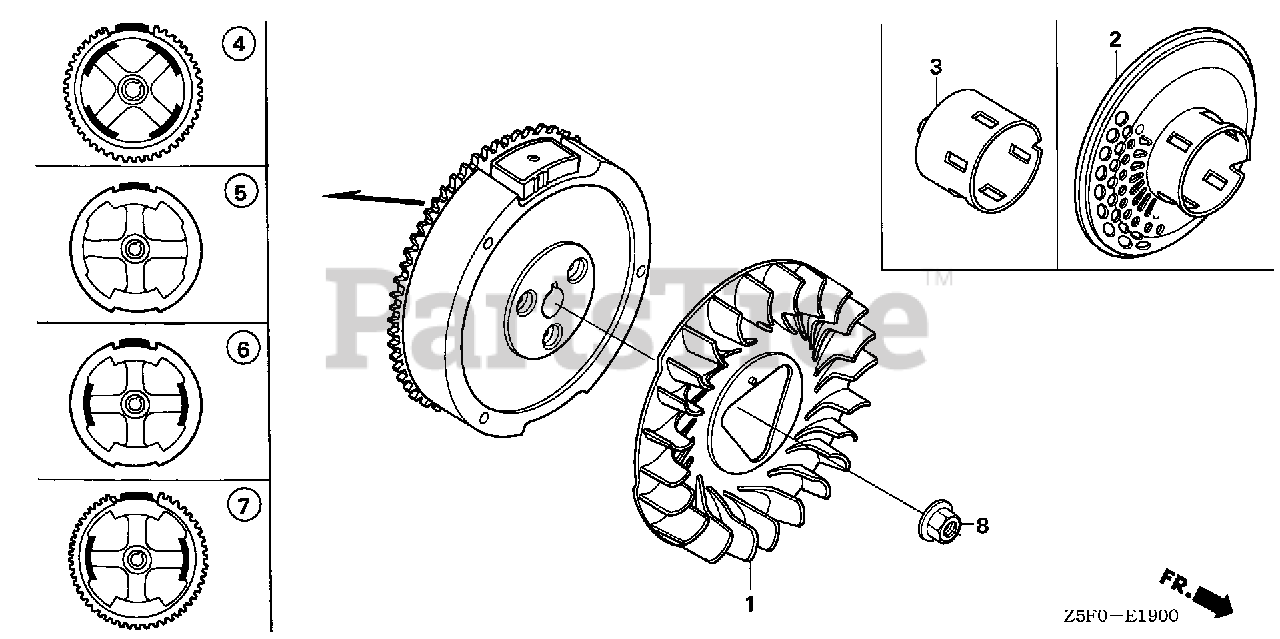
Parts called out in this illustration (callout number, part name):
1	FAN, COOLING
3	PULLEY, STARTER
5	FLYWHEEL
8	NUT, SPECIAL (16MM) (1)
8	NUT, SPECIAL (16MM)
